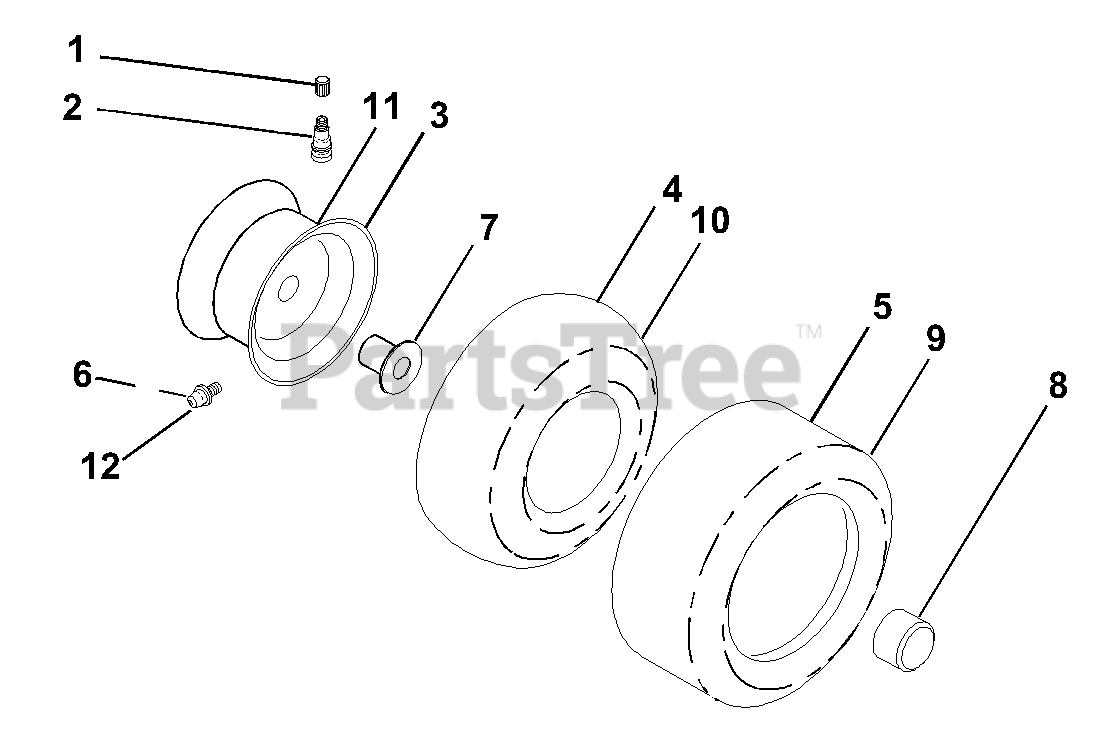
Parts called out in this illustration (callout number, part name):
1	Cap, Valve, Tire
2	Stem, Valve
3	Rim Assembly, Front
4	Tube, Front
5	Tire, Front
6	Fitting, Grease
7	Bearing, Flange
8	Cap, Hub
9	Tire, Rear
10	Tube, Rear
11	Rim Assembly, Rear
12	Fitting, Grease
